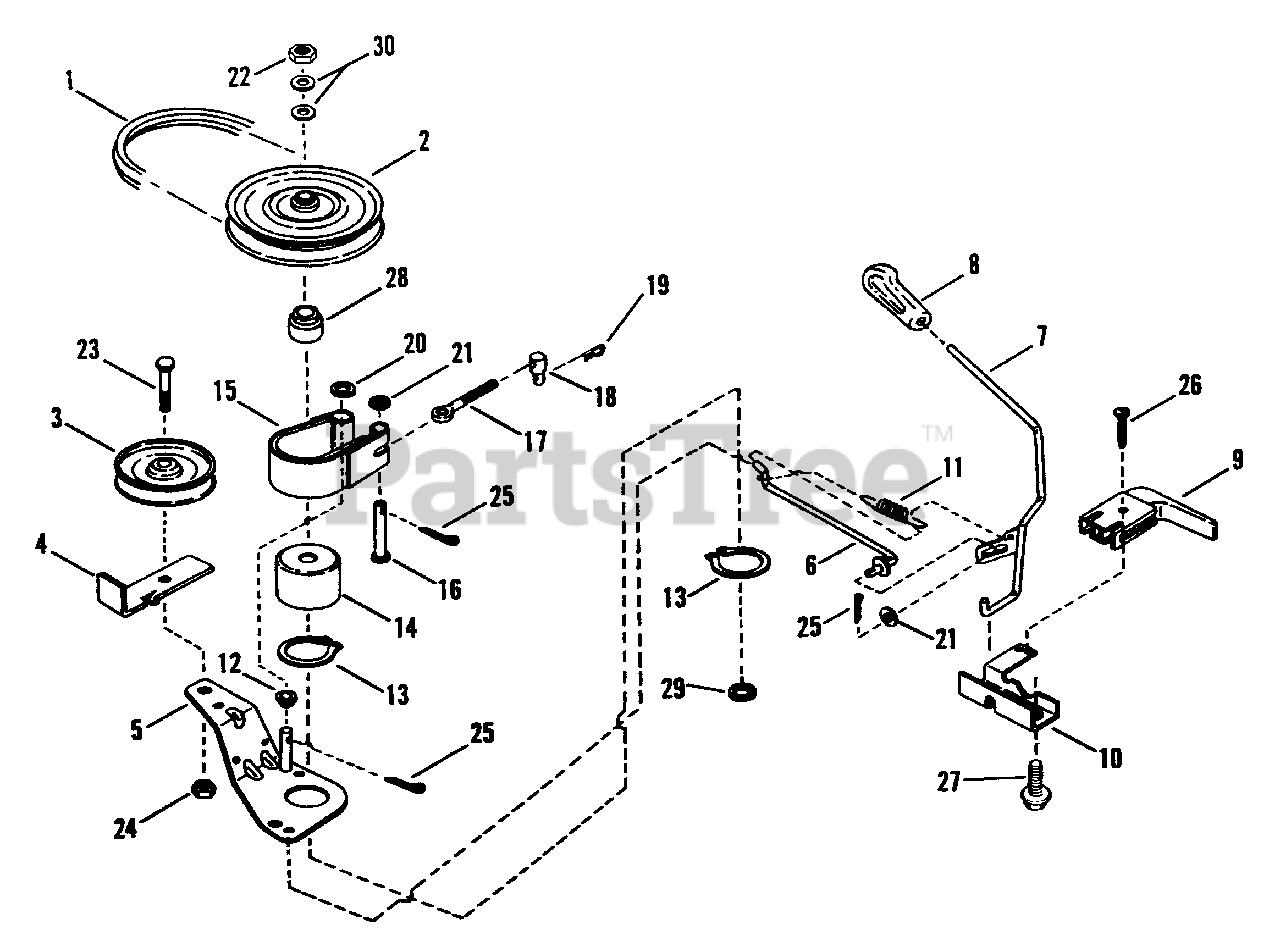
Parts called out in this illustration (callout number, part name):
1	BELT, Drive
2	PULLEY, Spindle
3	PULLEY, Idler
4	RESTRICTOR, Belt
5	ARM, Idler
6	ROD, Idler
7	HANDLE, Blade Lever (On-Off)
8	GRIP, Handle
9	SWITCH, Deck Interlock
10	MOUNT, Handle
11	SPRING, Blade Handle
12	SPACER
13	RING, 2" External Retaining
14	DRUM. Brake
15	BAND. Brake
16	PIN, 1/4 x 1-5/8 Clevis
17	BOLT, 5/16-18 x 3" Eye
18	SWIVEL Adjustable 1.6
19	PIN, 3/32 x 1-1/2 Hair
20	WASHER, 3/8" Flat
21	WASHER, 1/4 Flat
22	NUT, 3/4-16 Hex Jam
23	SCREW, 3/8-24 x 1-3/4 Hex Cap
24	NUT, 3/8-24 Hex Lock
25	PIN, 3/32 x 3/4 Cotter
26	SCREW, #10-32 x 1" Self-Tap
27	SCREW, 1/4-20 x 5/8 Self-Tap
28	HUB, Pulley
29	WASHER, Spindle
30	WASHER, 49/64 x 1-1/2" Flat
